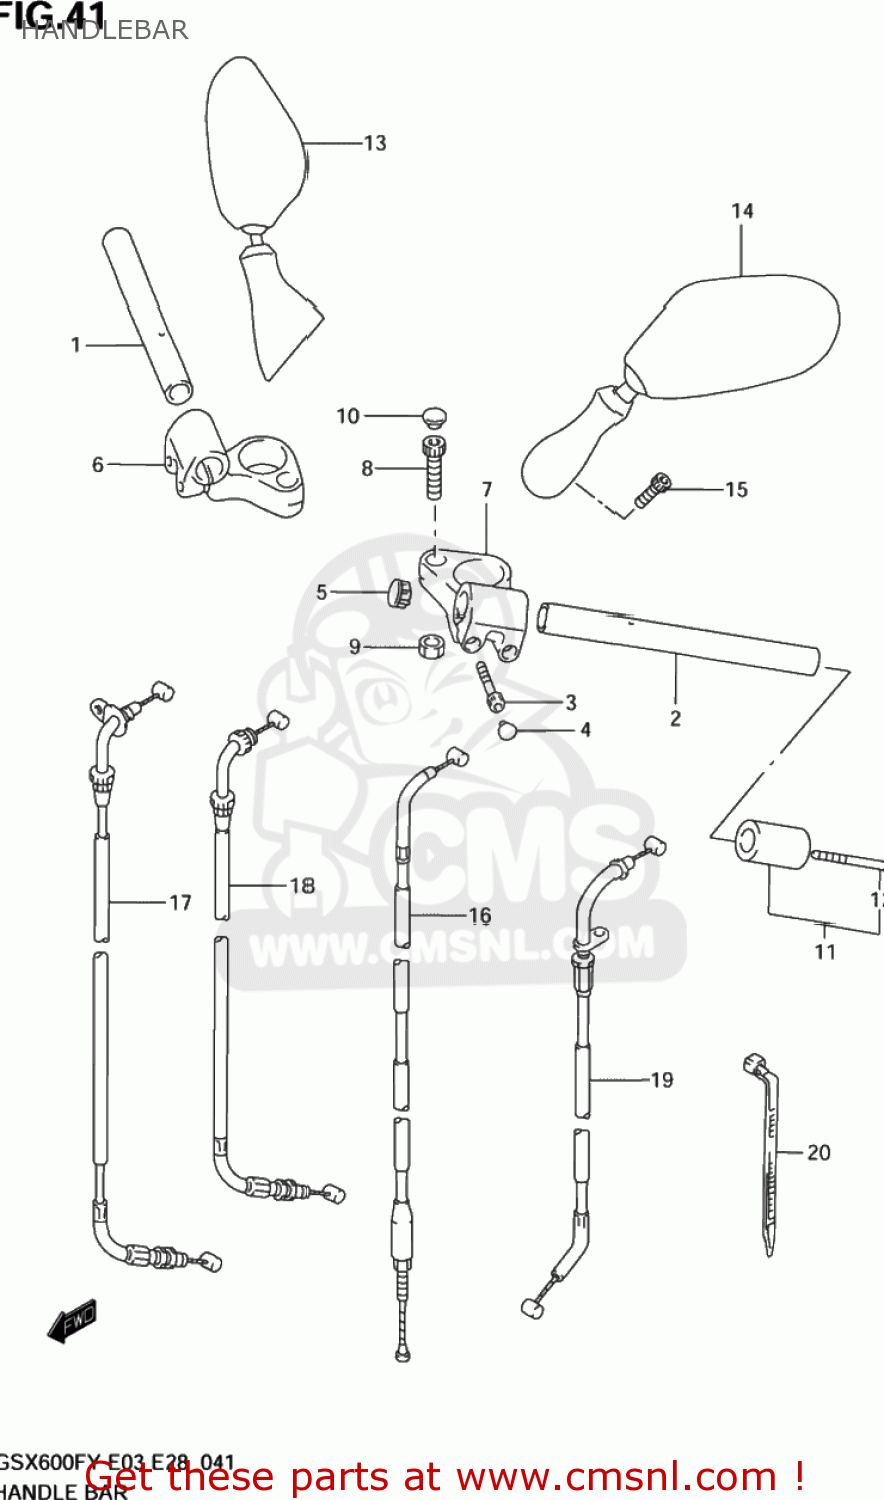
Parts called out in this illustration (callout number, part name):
1	HANDLEBAR,R
2	HANDLEBAR,L
3	BOLT
4	CAP(OD:10)
5	CAP,HANDLEBAR
6	HOLDER,HANDLEBAR,R
7	HOLDER,HANDLE,LEFT
8	BOLT 10X45
9	NUT
10	CAP(OD:20)
11	BALANCER SET,HANDLEBAR
12	SCREW
13	MIRROR ASSEMBLY,REAR VIEW
14	MIRROR ASSEMBLY,REAR VIEW
15	BOLT,OIL FILLE
16	CABLE ASSY,CLUTCH
17	CABLE ASSY,THROTTLE NO.1
18	CABLE ASSY,THROTTLE NO.2
19	CABLE,STARTER
20	CLAMP(L:165)
